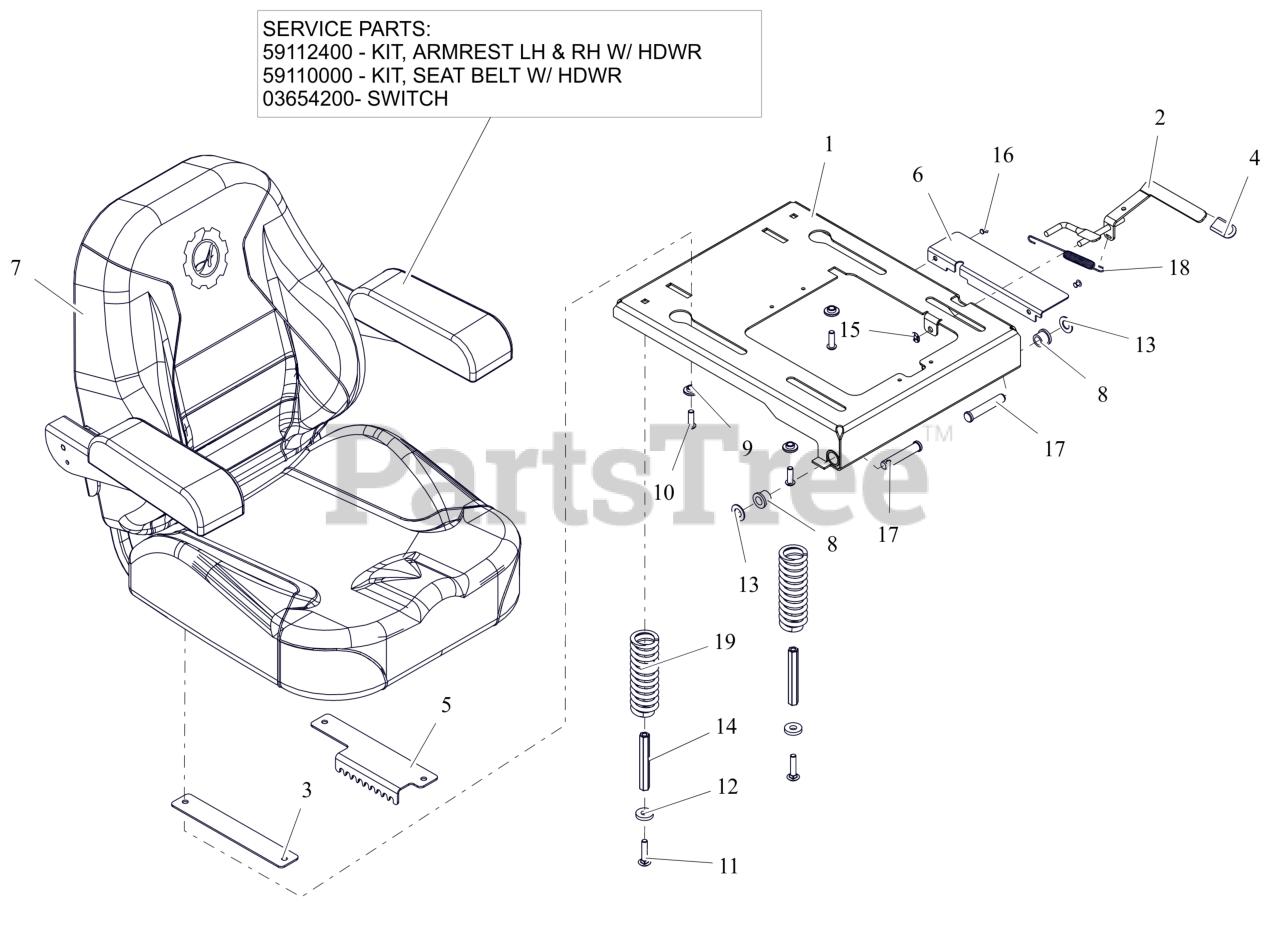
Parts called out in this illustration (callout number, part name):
1	WLDMT, SEAT PLATE HD
2	WLDMT, SEAT SLIDE LEVER
3	PLATE, ADJUSTABLE SEAT SLIDE
4	GRIP, SEAT LEVER, GREY
5	PLATE, HD SEAT ADJUSTMENT
6	GUARD, SEAT PLATE
7	SEAT, APEX
7	KIT-LH & RH ARM REST-05124700
7	KIT-SEAT BELT REPLACE-05007300
7	SWITCH- SEAT
8	BSHG, FLG .516X.750X.625X.937
9	BSHG-FLG .325X.499X.3X.875
10	BLT,SHCS-BTN .31-18X1.00 ZCC
11	BLT,RHSN .31-18X1.50 G5 ZCC
12	WSHR, FLT .406X1.00X.188 ZCC
13	WSHR, FLT .531X1.00X.063 ZCC
14	NUT, COUPLING 5/16X18 X 3.75
15	NUT-PUSH .312
16	RIVET, .1875 AL/AL .126-.250
17	PIN-CLIC .50X2.70X2.31 -ZCC
18	SG-TENS .06X.482X5.35
19	SPRING, COMPRESSION SEAT 224LB
